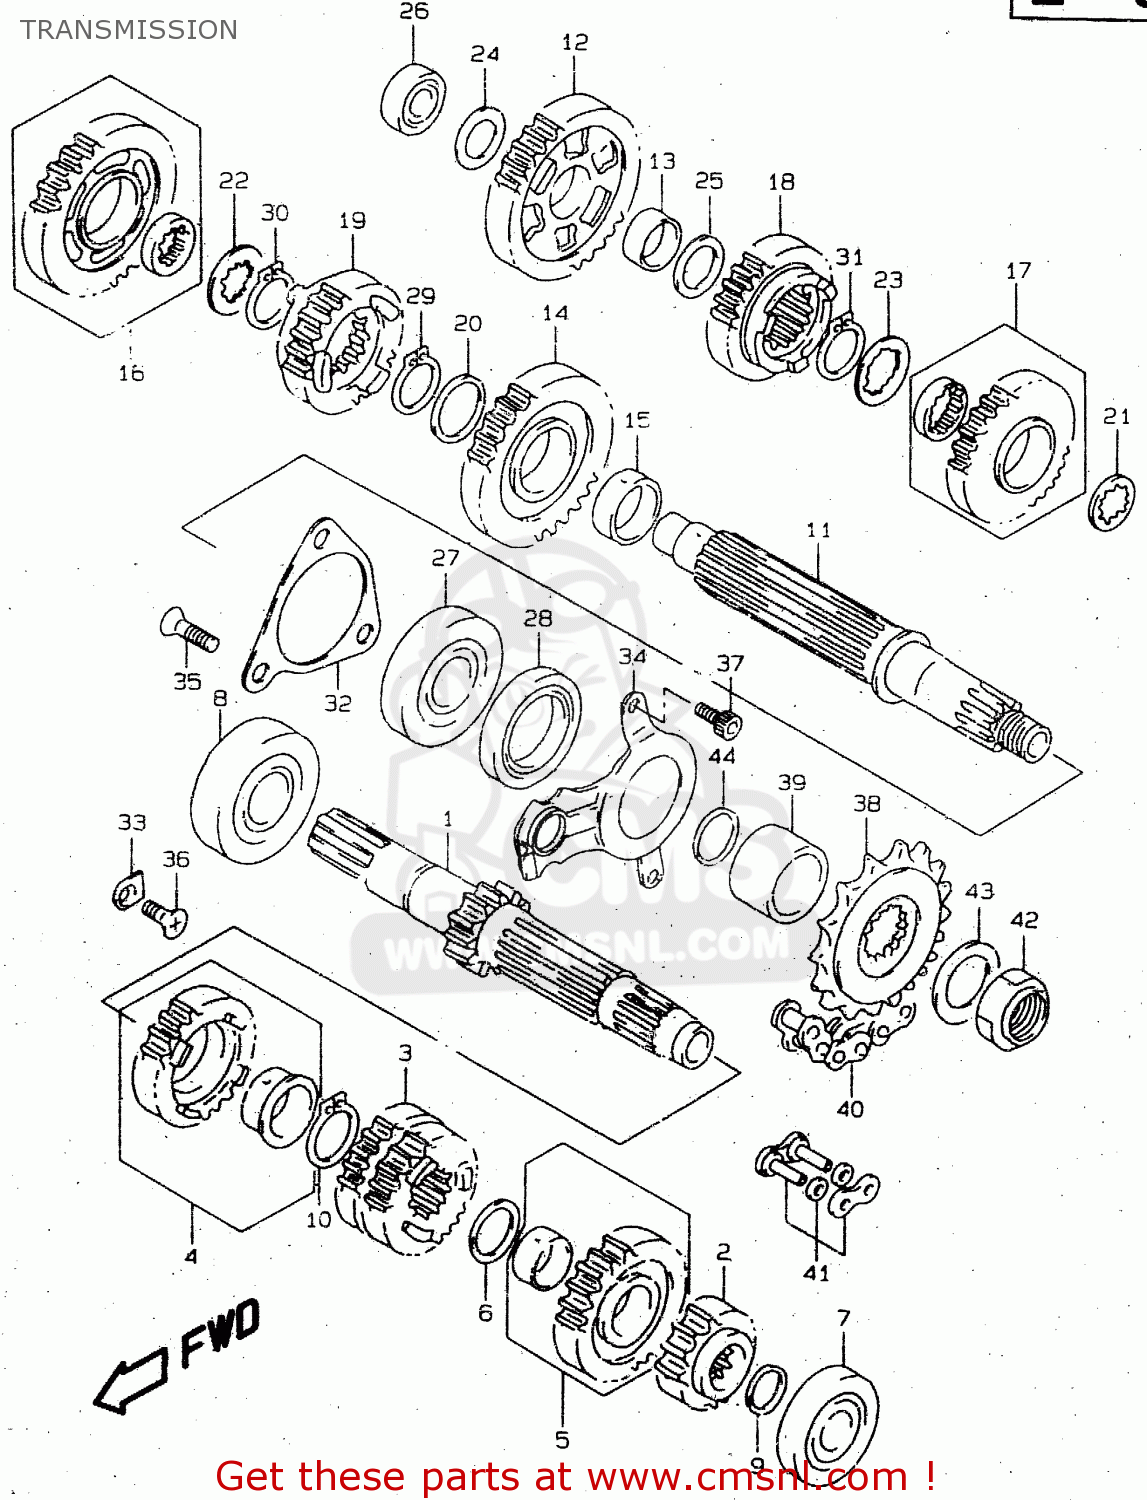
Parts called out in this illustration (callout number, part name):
1	SHAFT,COUNTER(NT:12)
2	GEAR,2ND DRIVE(NT:15)
3	GEAR,3RD & 4TH DRIVE(NT:18/27)
4	GEAR SET,FIFTH DRIVE (NT:
5	GEAR SET,SIXTH DRIVE (NT:
6	SHIM(22X30X1)
7	BEARING(20X47X14)
8	BEARING(25X62X17)
9	O RING(D:1.9,ID:16.6)
10	CIRCLIP
11	SHAFT,DRIVE
12	GEAR,1ST DRIVEN(NT:32)
13	BUSH
14	GEAR,2ND DRIVEN(NT:29)
15	BUSH,2ND DRIVEN GEAR
16	GEAR SET,THIRD DRIVEN (NT
17	GEAR SET,FOURTH DRIVEN (NT
18	GEAR,5TH DRIVEN(NT:25)
19	GEAR,SIXTH DRIVEN (NT:24)
20	WASHER(27X36X1)
21	WASHER,LOCK
22	WASHER,3RD & 4TH DRIVEN
23	WASHER,3RD & 4TH DRIVEN
24	SHIM(20X34X1)
25	SHIM(22X34X1)
26	BEARING(20X52X15)
27	BEARING(28X68X20)
28	SEAL,OIL(38X52X8)
29	CIRCLIP
30	CIRCLIP
31	CIRCLIP
32	RETAINER,DRIVE SHAFT BEARING
33	RETAINER
34	RETAINER,DRIVESHAFT O
35	SCREW(6X12)
36	SCREW
37	BOLT,STRANGER
38	SPROCKET,ENGINE (NT:17)
39	SPACER,ENGINE SPROCKET
40	CHAIN ASSEMBLY RK50GSVZ1.1
41	JOINT SET,DRIVE CHAIN
42	NUT
43	SHIM(25X40X1.5)
44	O RING(D:2.4,ID:23.7)
